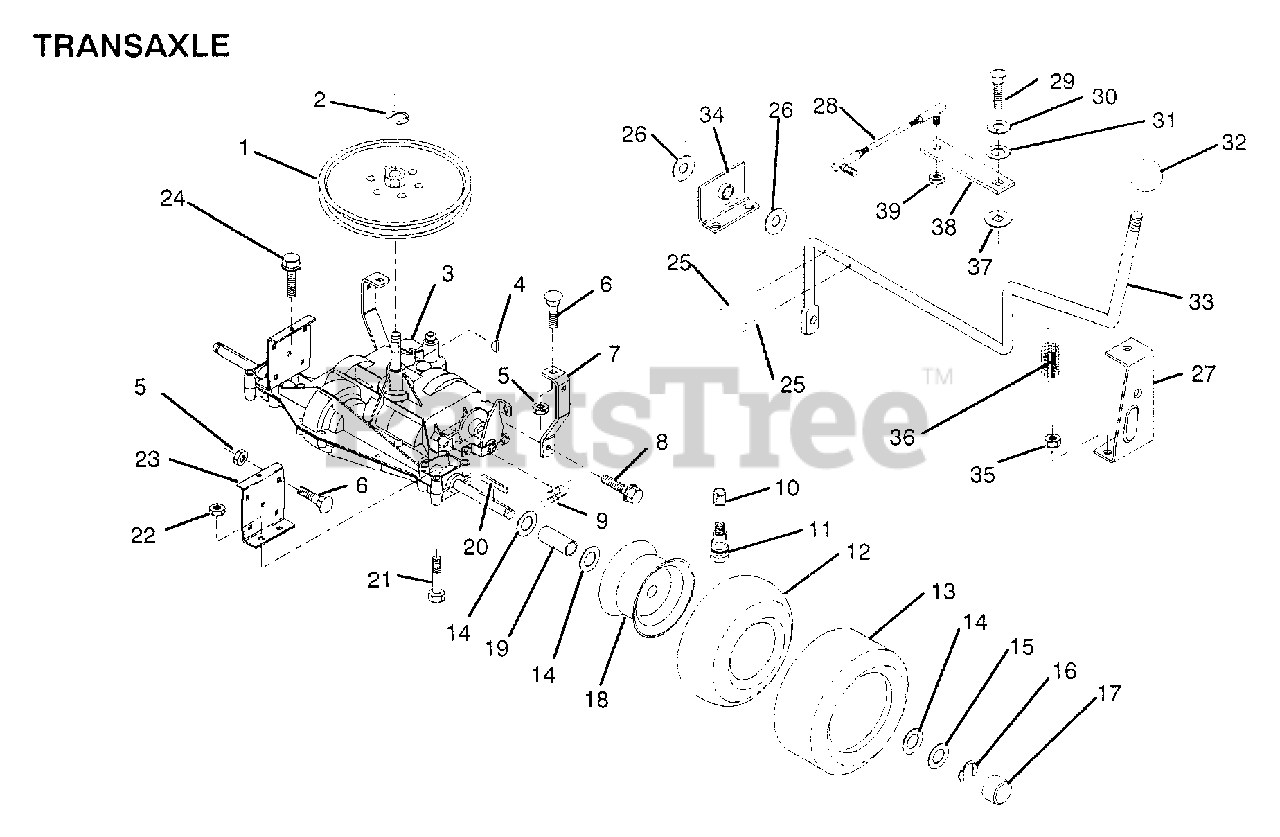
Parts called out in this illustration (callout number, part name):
1	PULLEY
6	BOLT
7	"STRAP,TORQUE"
8	SCREW LT
10	VALVE CAP
11	VALVE STEM LT
12	TUBE.16X6.5/7.5-8
14	WASHER
15	WASHER
16	E-RING LT
17	HUB CAP
19	SPACER
20	SQUARE KEY
21	BOLT
23	"BRKT,TRANSAXLE"
24	SCREW
25	PIN COTTER 1/8
28	"LINK,SHIFT"
30	LOCKWASHER
31	WASHER LT
32	KNOB T (1/2-HOLE)
34	"SUPT,HDLE SHT LH"
36	EXT SPRING
37	WASH-SHFT PLT LT
38	ARM SHIFT
39	NUT.LOCK.5/16-24
